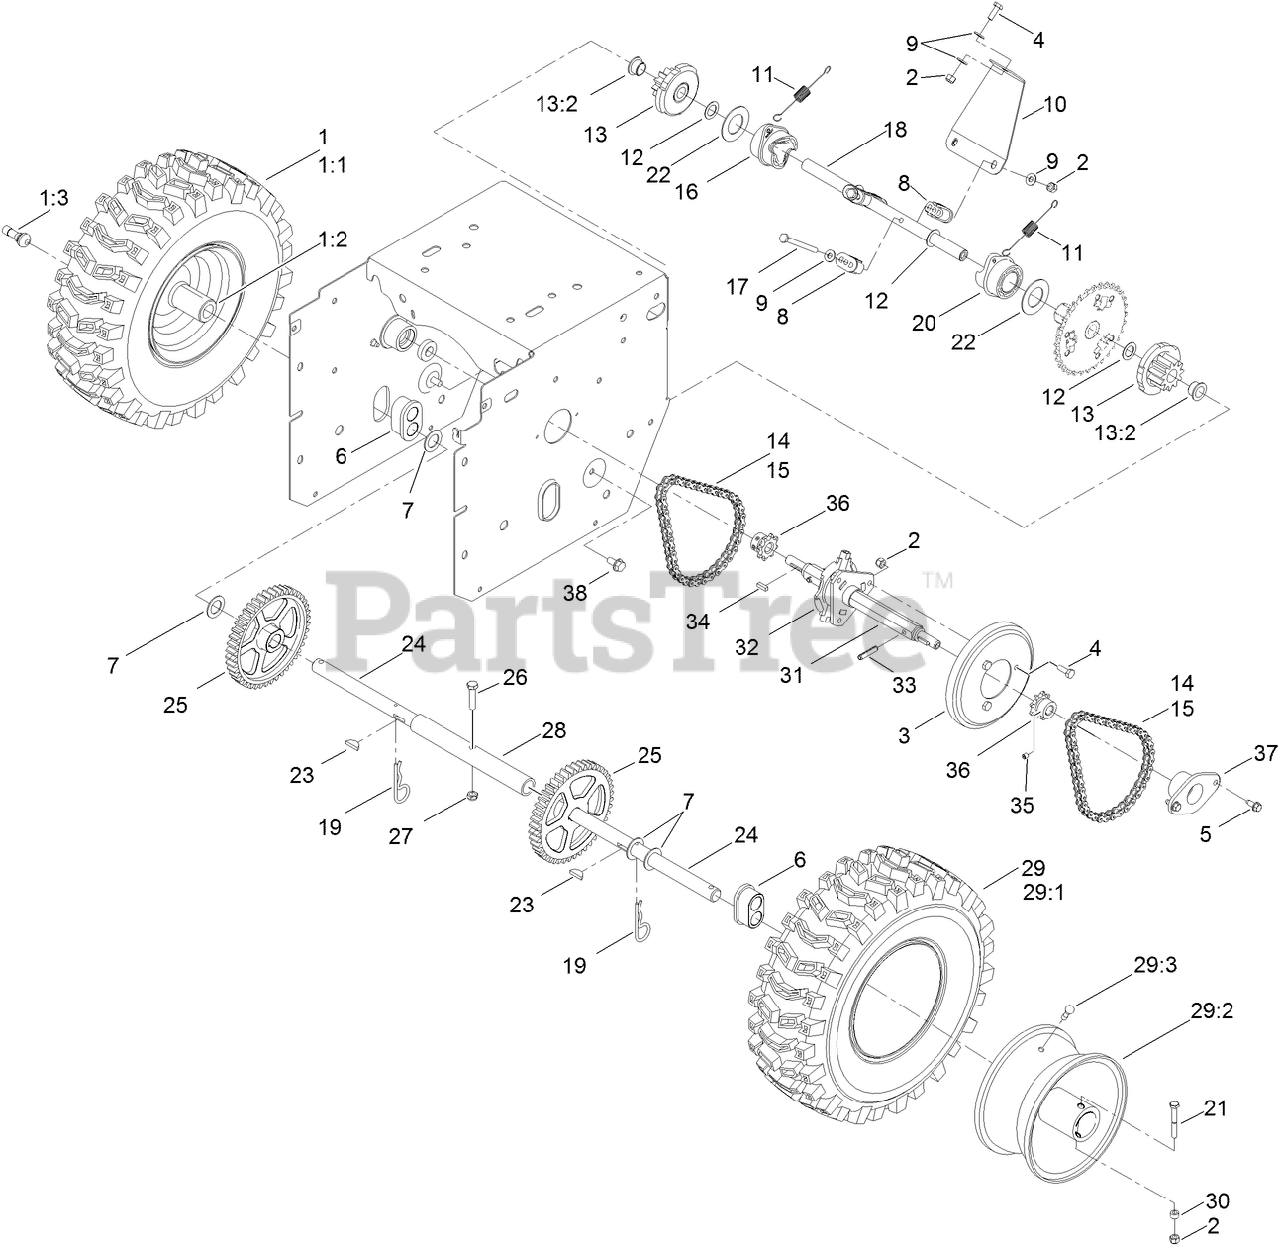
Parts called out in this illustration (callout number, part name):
1	RH WHEEL AND TIRE ASM
1:2	RIM-TIRE
1:3	STEM-VALVE
2	NUT-LOCK, NI
3	WHEEL-FRICTION
4	SCREW-HH
5	SCREW-HWH
6	BEARING-AXLE
7	WASHER-THRUST
8	GUIDE-COLLAR
9	WASHER-FLAT
10	BRACE-COLLAR, SHIFT
11	SPRING-EXTENSION
12	WASHER-FLAT
13	11T GEAR ASM
13:2	BUSHING-FLANGE
14	CHAIN-ROLLER
15	LINK-CONNECTING
16	COLLAR-SHIFT, RH
17	SCREW-HH
18	SHAFT-INTERMEDIATE
19	PIN-HAIR
20	COLLAR-SHIFT, LH
21	SCREW-HH
22	WASHER-THRUST
23	KEY-WOODRUFF
24	SHAFT-AXLE
25	GEAR-AXLE, 44 TOOTH
26	SCREW-HH
27	NUT-LOCK, NI
28	TUBE-AXLE
29	LH WHEEL AND TIRE ASM
29:2	RIM-TIRE
29:3	STEM-VALVE
30	SPACER-BLADE, ROTOR
31	SHAFT-HEX
32	TRUNNION-HEX
33	PIN-ROLL, SLOTTED
34	KEY-SQUARE
35	SCREW-HSH
36	SPROCKET-8 TOOTH
37	RETAINER-BEARING
38	SCREW-HWHTF
